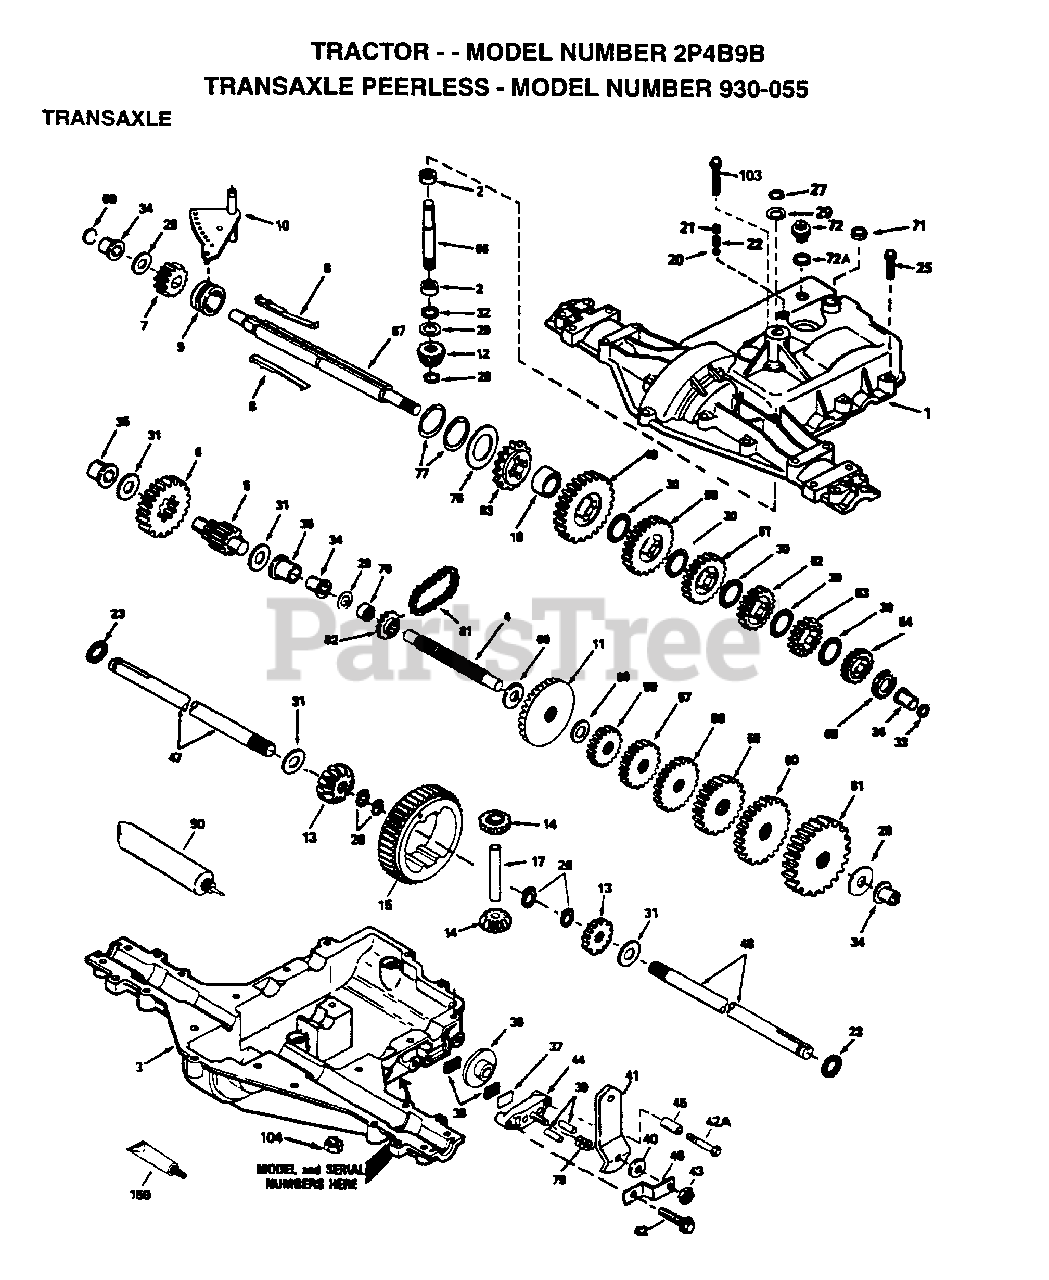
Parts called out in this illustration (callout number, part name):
1	TRANSAXLE COVER
2	BEARING, NEEDLE
3	TRANSAXLE CASE
4	SHAFT, COUNTER
5	OUTPUT SHAFT AND PINION
6	GEAR, OUTPUT
7	GEAR, SPUR, 15 TEETH
9	COLLAR, SHIFTER
10	ROD & FORK ASSY, SHIFT
11	GEAR, BEVEL, 42 TEETH
12	BEVEL PINION, INPUT
13	GEAR, BEVEL
14	GEAR, BEVEL, PINION
18	SPACER, NEUTRAL
20	BALL STEEL, 5/16" DIA.
21	SCREW, 3/8-16 X 3/8"
25	SCREW, 1/4-20 X 1-1/4
26	RING RETAINER
27	RING, RETAINER
28	RETAINING RING
29	WASHER THRUST
30	WASHER THRUST
33	SEAL, SQUARE CUT
34	BUSHING, FLANGED
35	BUSHING, FLANGED
36	DISK, BRAKE
37	PLATE BRAKE PAD
41	BRAKE LEVER
42	SCREW, 1/4-20 X 1-1/4
42A	SCREW, 1/4-20 X 2-1/4
43	LOCKNUT 5/16-24
44	HOLDER BRAKE PAD
46	BRKT BRAKE LEVER
49	GEAR, SPUR, 37 TEETH
50	GEAR, SPUR, 35 TEETH
51	GEAR, SPUR, 30 TEETH
52	GEAR, SPUR, 25 TEETH
53	GEAR, SPUR, 22 TEETH
54	GEAR, SPUR, 19T
56	GEAR, SPUR, 12 TEETH
57	GEAR, SPUR, 15 TEETH
58	GEAR, SPUR, 20 TEETH
59	GEAR, SPUR, 25 TEETH
60	GEAR, SPUR, 28 TEETH
61	GEAR, SPUR, 31 TEETH
65	WASHER, THRUST
66	SHAFT, INPUT
67	SHAFT, BRAKE, 4 KEYED
69	WASHER THRUST
71	SEAL SQUARE CUT
72	THREADED PLUG 9/16-18
76	WASHER, THRUST
77	INVERTED RETAINING RING
81	CHAIN, ROLLER
82	SPROCKET 9T
83	SPROCKET 18T (REV)
90	GREASE BENTONITE, 32 OZ.
150	GASKET ELIMINATOR
